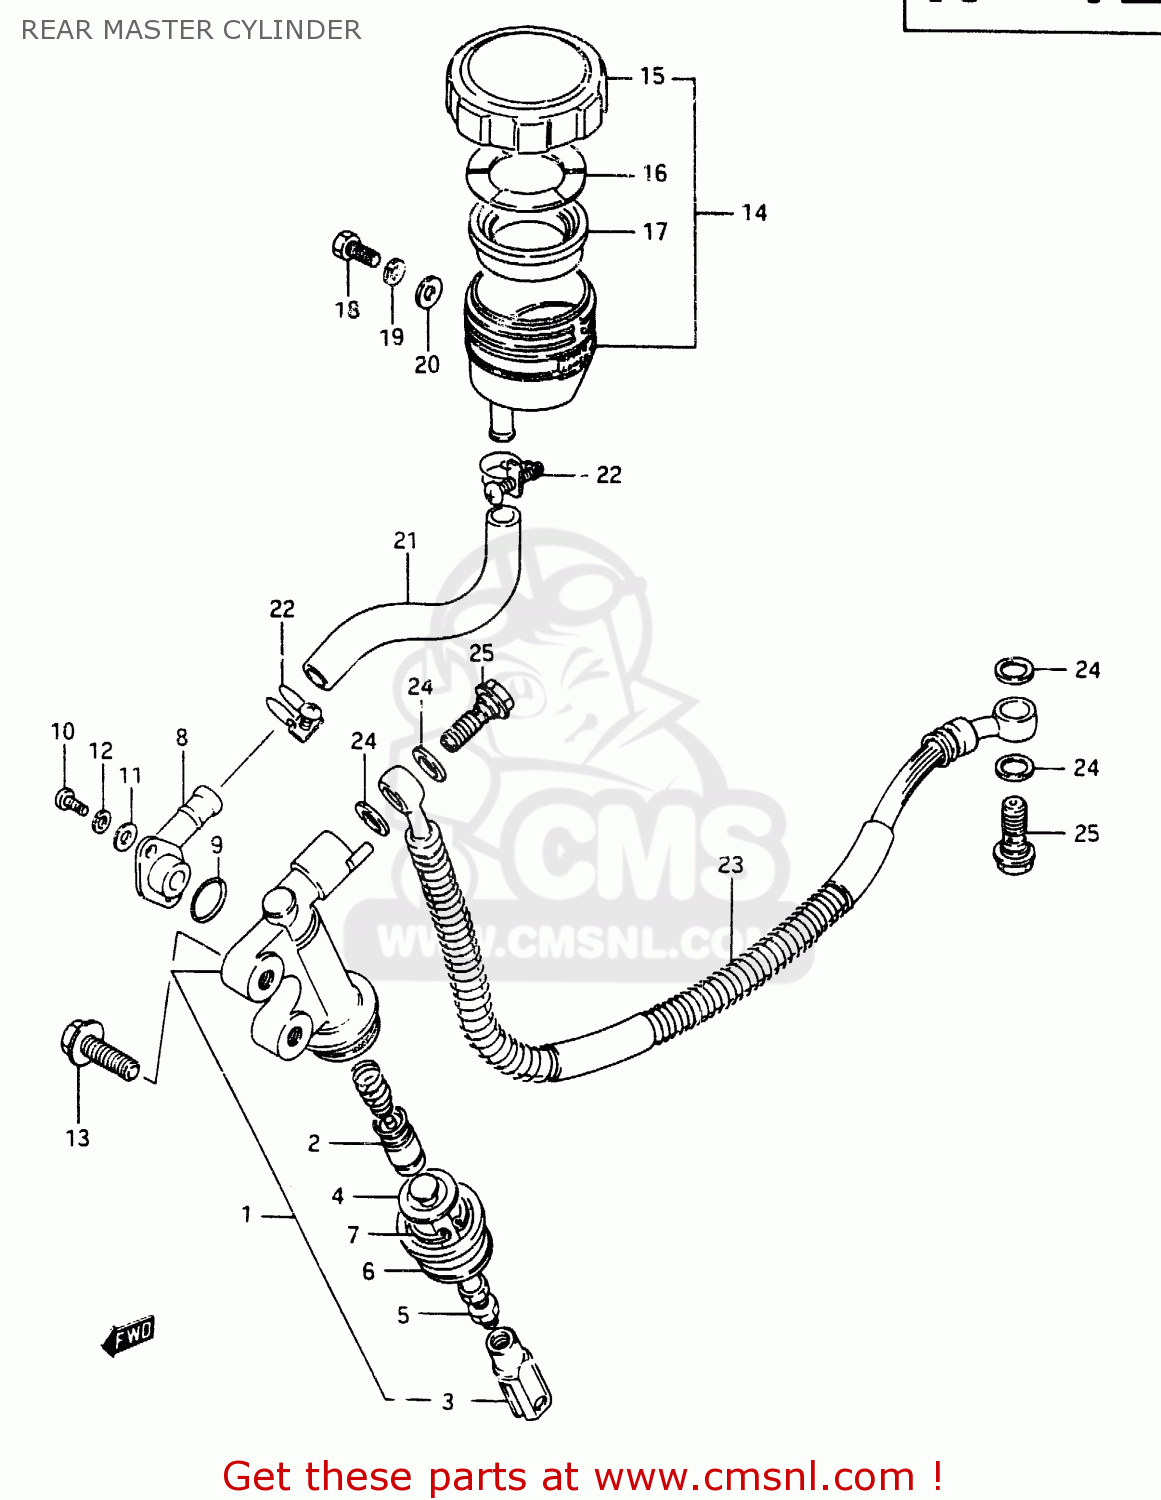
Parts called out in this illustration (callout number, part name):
1	CYLINDER ASSY,RR MASTER
2	PISTON/CUP SET
3	YOKE
4	ROD,PUSH
5	NUT,MASTER CYLINDER
6	BOOT
7	CIRCLIP
8	CONNECTOR,HOSE
9	O RING
10	SCREW
11	WASHER
12	LOCK WASHER
13	BOLT
14	TANK ASSEMBLY,RESERVOIR
15	CAP
16	PLATE,DIAPHRAGM
17	DIAPHRAGM
18	SCREW(6X12)
19	WASHER,LOCK
20	WASHER
21	HOSE,RESERVOIR TANK
22	CLAMP
23	HOSE,REAR BRAKE
24	WASHER(10X15X1.5)
25	BOLT UNION
